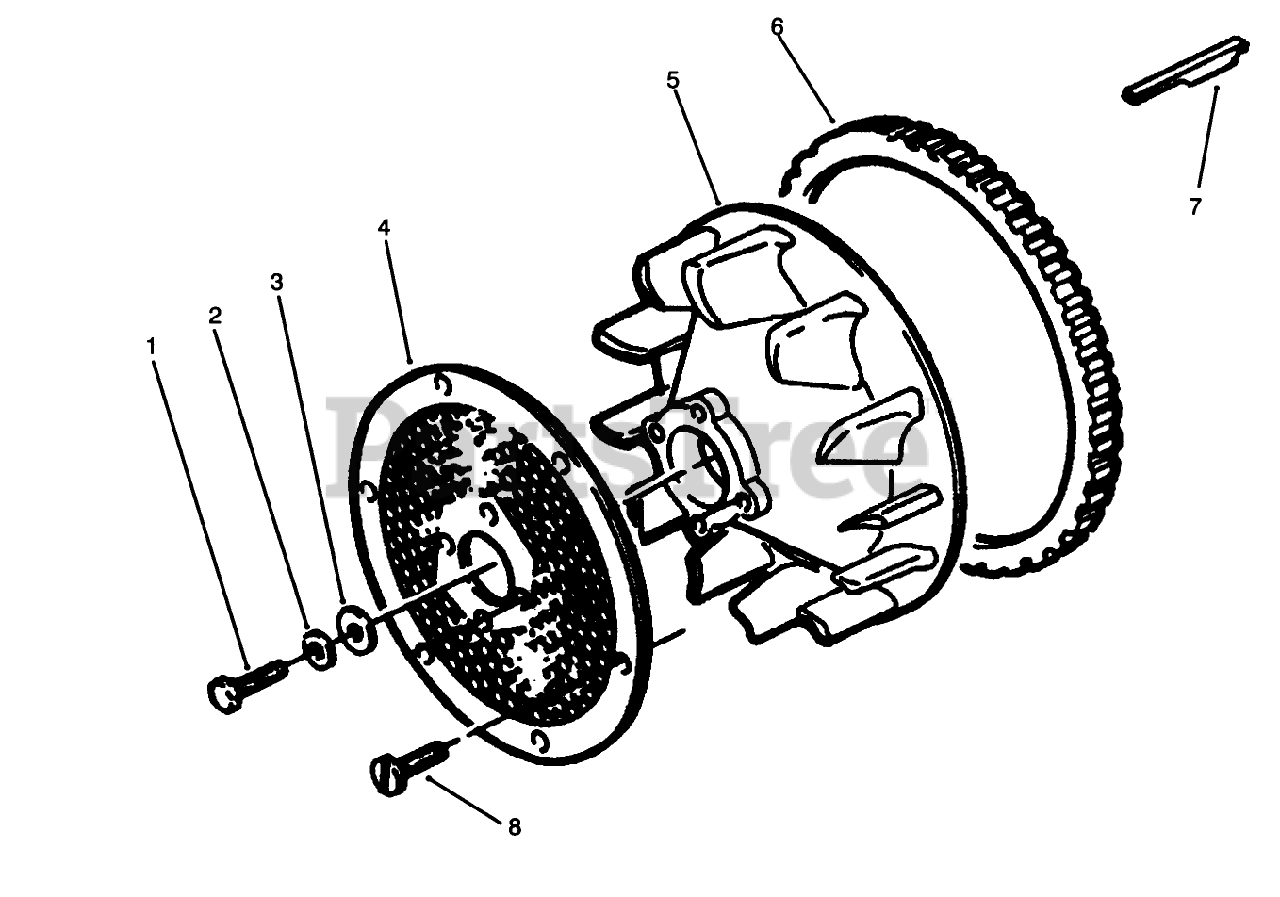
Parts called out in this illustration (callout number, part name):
2	WASHER-FLAT
3	WASHER-FLAT
4	SCREEN-AIR INLET
7	KEY-FLYWHEEL
